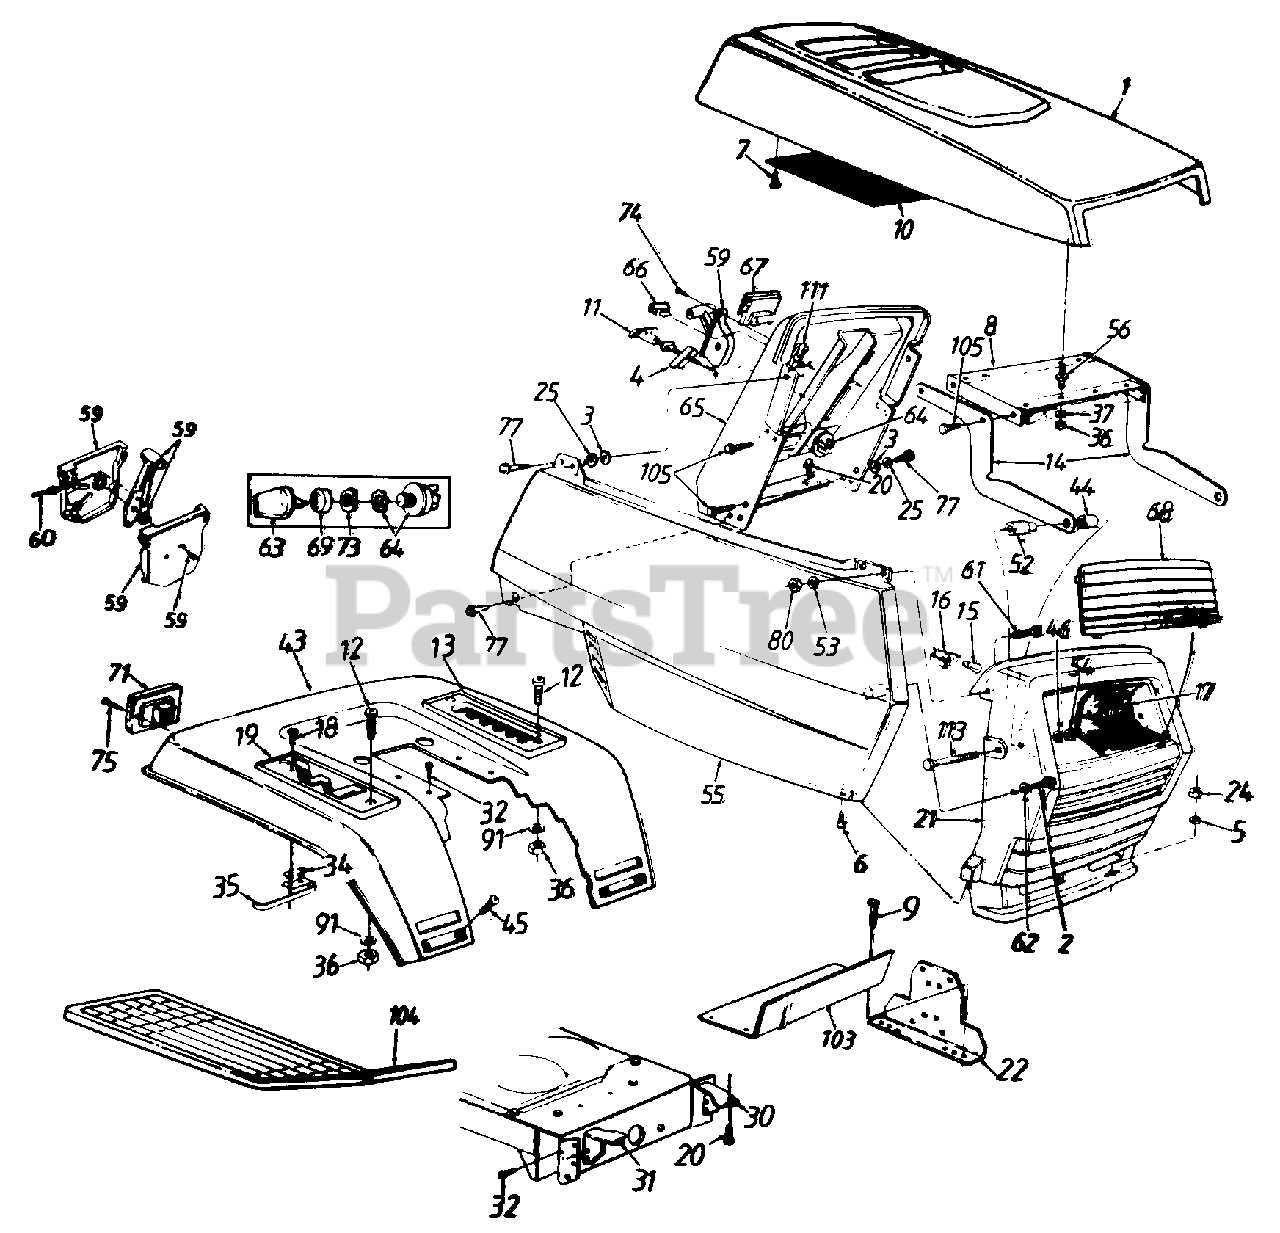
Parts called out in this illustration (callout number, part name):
3	Bolt Retainer 1/4" I.D.
4	Retainer Clip
5	Fl-Wash. .34" I.D. x 1" O.D.
6	Truss Mach. AB-Tap Scr. #10 x .5" Lg.
7	Hex Wash Hd. AB-Tap Scr. #8 x .5" Lg.
8	Hood Plate
9	Hex Wash. Hd. B-Tap Scr. 5/16-18 x .5" Lg.
11	Choke Control
12	Truss Mach. Scr. 1/4-20 x .75" Lg.
13	7-Speed Index Brkt.
14	Hood Hinge
15	Lamp
16	Twist Lock - Lamp Socket
17	Reflector - Headlight
18	Hex Wash. Hd. AB-Tap Scr. #8 x .5" Lg.
19	Forward/Reverse Index Brkt.
20	Hex Bolt 5/16-18 x .75" Lg.
21	Grille
24	Hex Nut 5/16-18 Thd.
25	Fl-Wash. 1/4" I.D. x .93" O.D.
30	Grille Mount Brk't. - L.H.
31	Grille Mount Brk't. - R.H.
32	Hex Wash. Hd. AB-Tap Scr. 5/16 x .75" Lg.
34	Insulator Nut Plate
35	Reverse Safety Switch
36	Hex Nut 1/4-20 Thd.
37	Bell-Wash. .265" I.D. x .75"
45	Carriage Bolt 1/4-20 x .50" Lg.
46	Fl-Wash. .328" I.D. x .68" O.D.
52	Shld. Spacer .33" I.D.
53	Fl-Wash. .281" I.D. x .5" O.D.
55	Side Cover - R.H.
56	Double Ended Stud 1/4-20 Thd.
59	Throttle Control Box Ass'y.
60	Throttle Control Wire
61	Hex Bolt 1/4-20 x .62" Lg.
62	Fl-Wash. .281" I.D. x .73" O.D.
64	Ignition Switch
65	Dash Panel
66	Light Switch
67	Ammeter
68	Lens
69	Ignition Switch Cap
71	Taillight
73	Ignition Switch Nut
74	Truss Mach. AB-Tap Scr. #10 x .5" Lg.
75	Truss Hd. AB-Tap Scr. #6 x .62" Lg.
77	Hex Wash. Hd. Tap Scr. 1/4 x .75" Lg.
80	Hex L-Nut 1/4-20 Thd.
91	L-Wash. 1/4" I.D.
105	Hex Tap Scr. 1/4-20 x .5" Lg.
111	Speed Nut 1/4-20 Thd.
113	Hex Bolt 5/16-18 x 2.75"
